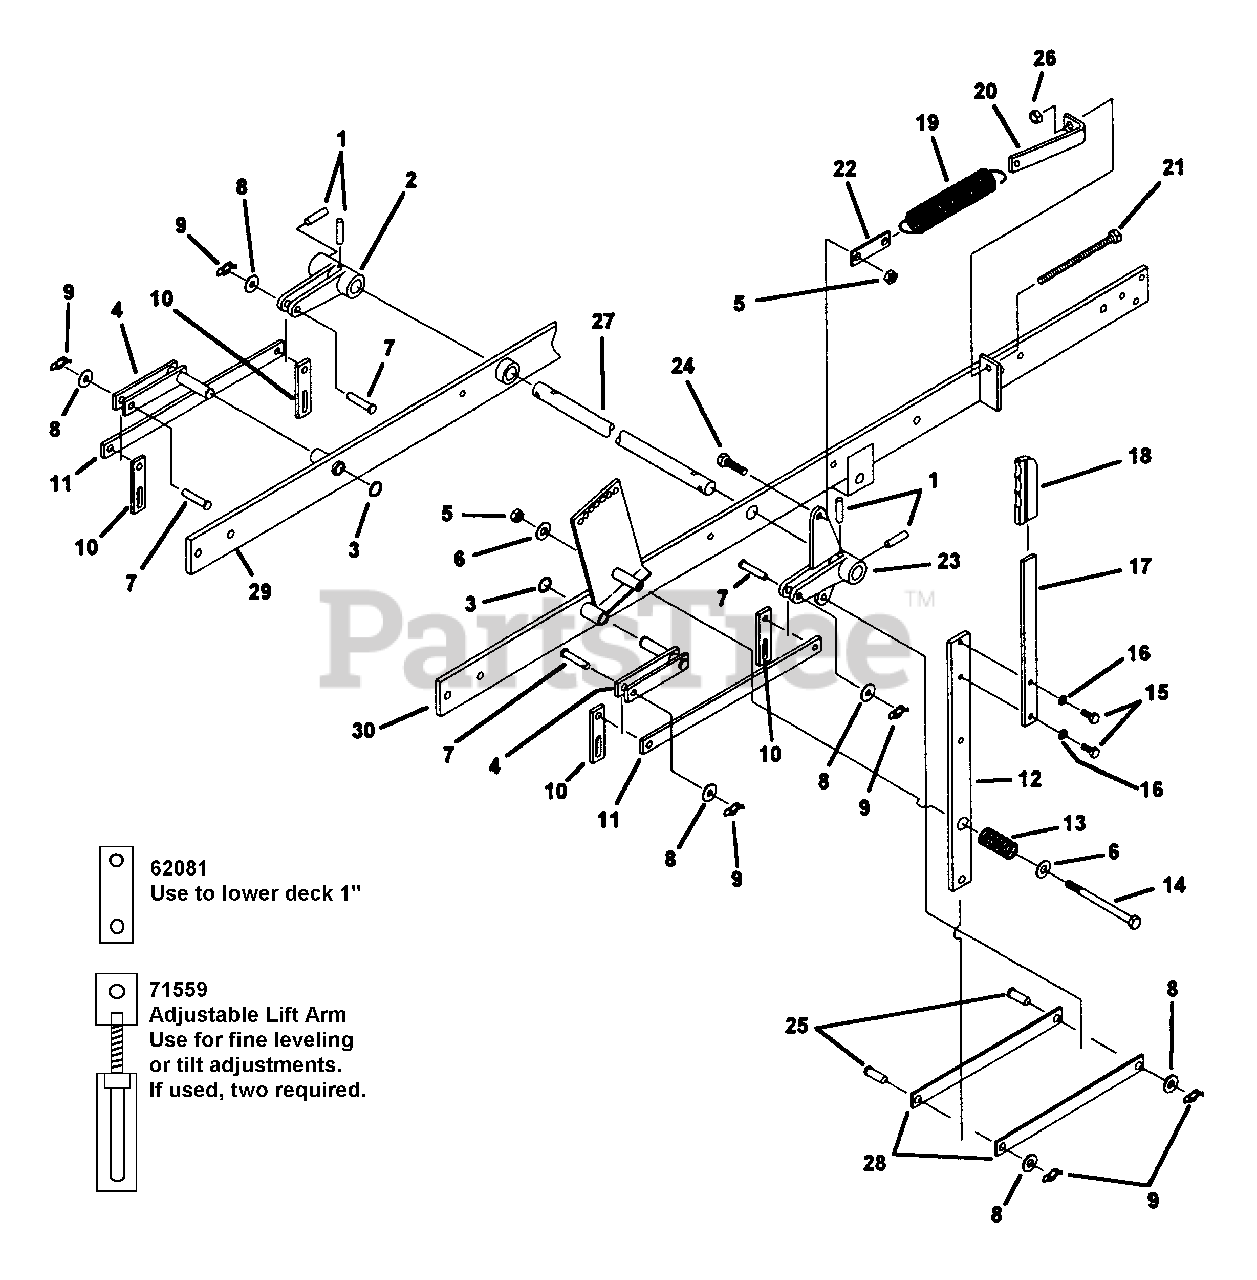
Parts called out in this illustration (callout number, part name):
1	ROLL PIN, 5/16 X 1-1/4 HBK
2	LIFT SLEEVE WELDMENT, R.H.
3	RING, 5/8" External Retaining
4	DECK HANGER WELDMENT
5	NUT, 3/8-16, NYLOC
6	WASHER, FLAT STD. 3/8"
7	CLEVIS PIN, 5/16 X 1-1/2" LONG
8	WASHER, FLAT STD. 5/16"
9	COTTER RUE RING, 5/16-3/8
10	DECK HANGER BAR
11	BAR, CONNECTING
12	LOWER HANDLE WELDMENT
13	SPRING, COMPRESSION, .975 O.D.
14	BOLT, 3/8-16 X 3" GR. 5
15	BOLT, 1/4-20 X 3/4" GR. 5
16	LOCKWASHER, 1/4" SPLIT SPRING
17	TOP DECK HANDLE
18	GRIP, HANDLE
19	SPRING, EXT., 1.65 O.D. X 9"
20	SPRING TIGHTENER
21	BOLT, 3/8-16 X 5" FULL THREAD
22	SPRING EXTENSION
23	LIFT SLEEVE WELDMENT, L.H.
24	BOLT, 3/8-16 X 1-1/4" GR. 5
25	CLEVIS PIN, 3/8 X 1"
26	NUT, HEX. 3/8-16 UNC-2B
27	LIFT BAR
28	HANDLE LINK
29	FRAME SIDE WELDMENT, R.H.
30	FRAME SIDE WELDMENT, L.H.
62081	BAR, DECK HANGER
71559	ARM, LIFT, ADJUSTABLE
